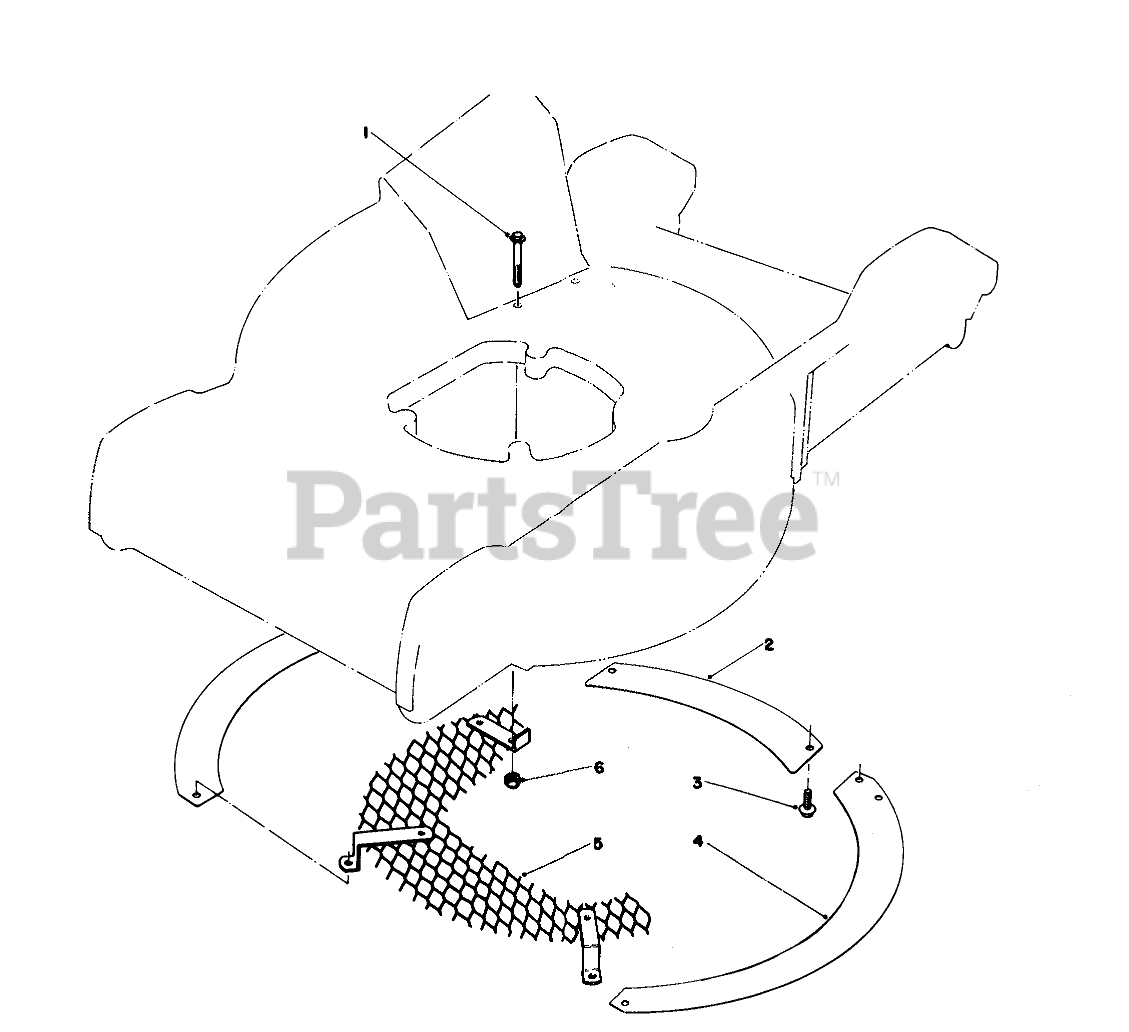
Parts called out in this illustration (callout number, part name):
1	Screw
2	Rear Baffle
3	SCREW
4	Outer Baffle
5	Screen
6	NUT-LOCK
